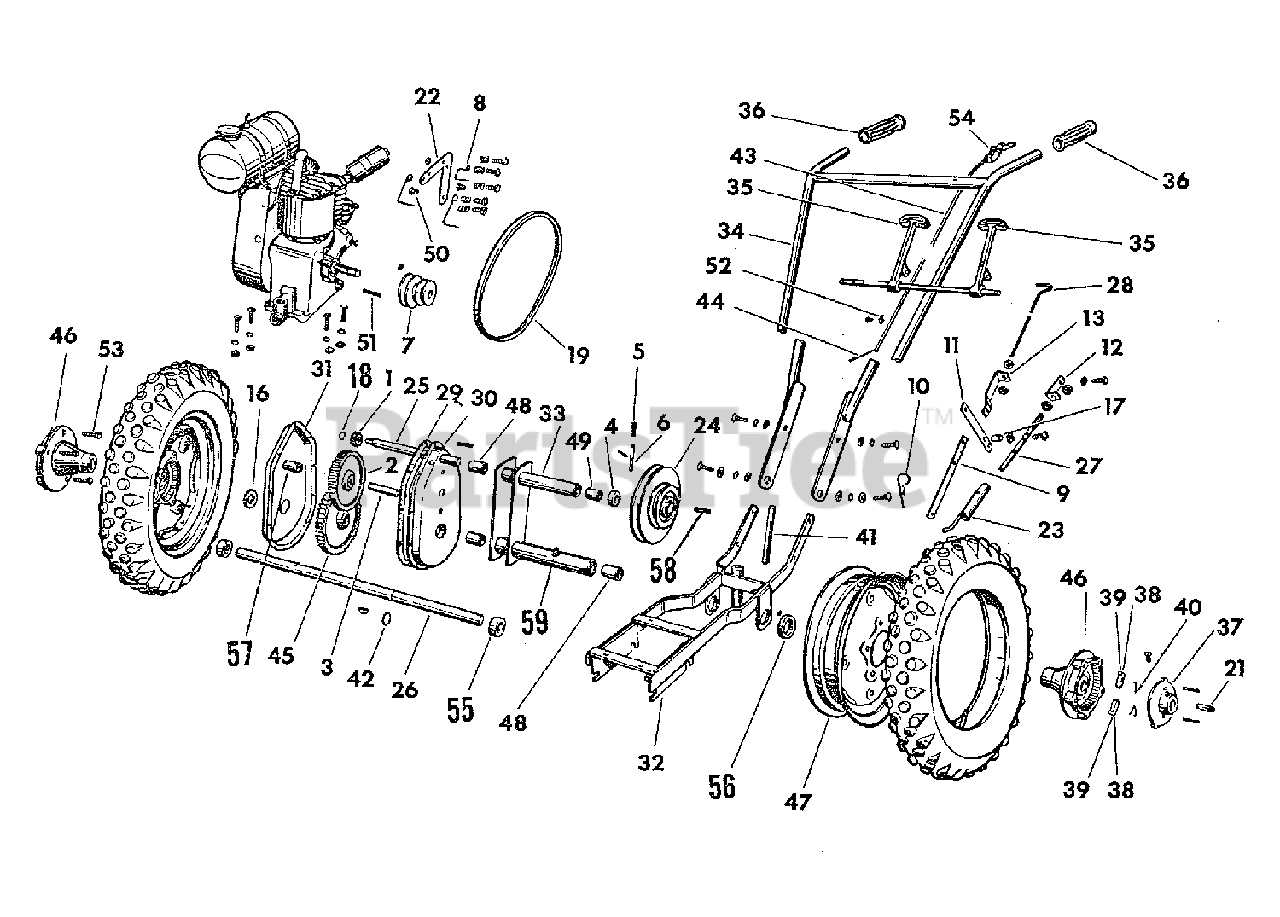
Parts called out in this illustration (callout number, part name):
1	PINION, Reduction
2	GEAR, Cluster
3	SPINDLE, Intermediate
4	COLLAR, Set
5	SPRING, Transmission Sheave
6	PIN, Transmission Sheave
7	PULLEY, Engine
8	STOP, Belt
9	FRAME, Extension
10	PIN, Speed Change
11	LEVER, Lower Clutch
12	ROD END, Variable Clutch
13	ROD END, Clutch
17	BUSHING, Stop
18	RING, Retaining
19	BELT, Transmission, 40"
20	SHAFT, Lever
21	RATCHET CAGE, Key
22	HOLDER ASSEMBLY, Belt Stop
23	SOCKET ASSEMBLY, Throw-Out
24	SHEAVE, Transmission
25	SHAFT, Pulley
27	ROD, Throw-Out
28	ROD, Clutch
29	GASKET, Gear Housing
30	CASE, Gear
31	COVER, Gear Case
32	FRAME ASSEMBLY
33	BEARING HOUSING ASSEMBLY
34	HANDLE ASSEMBLY
35	LEVER, Clutch
36	GRIP, Handle
37	CAGE, Ratchet
38	RATCHET DOG, Right
39	RATCHET DOG, Left
41	PIN, Draw Bar
42	RING, Retaining
43	WIRE HOUSING, Throttle Control
44	WIRE, Throttle Control
45	GEAR, Drive
46	HUB, Wheel
48	BUSHING, Axle
49	BUSHING, Pulley Shaft
51	KEY, Engine Sheave
52	CLAMP, Cable
53	BOLT, Rim
54	LEVER ASSEMBLY, Throttle
55	SET COLLAR, Axle
56	SET COLLAR, Axle Housing
57	BUSHING, Intermediate
58	KEY, Transmission Sheave
